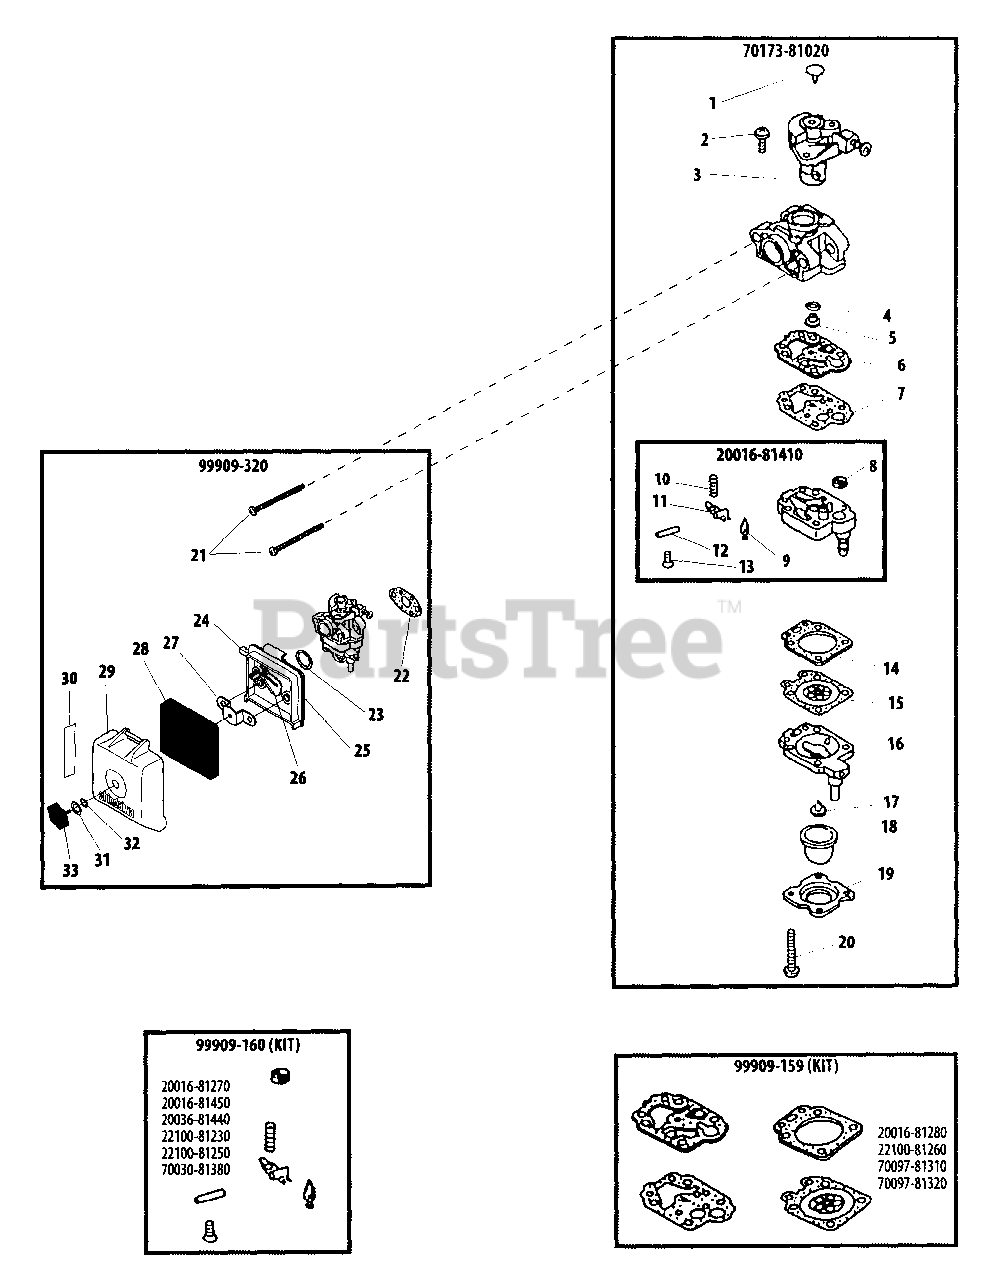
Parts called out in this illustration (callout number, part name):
1	PLUG
2	SCREW, THROTTLE COLLAR
3	THROTTLE VALVE ASSY
4	O-RING
5	MAIN JET - #38
6	GASKET, PUMP
7	DIAPHRAGM, PUMP
8	SCREEN, FUEL INLET
9	VALVE, INLET NEEDLE
10	SPRING, METERING LEVER
11	LEVER, METERING
12	PIN, METERING LEVER
13	SCREW
14	GASKET, METERING DIAPHRAGM
15	DIAPHRAGM, METERING
16	BODY ASSY, PURGE
17	VALVE, CHECK
18	BULB, PURGE
19	RETAINER, PURGE BULB
20	SCREW
21	SCREW - 5×67
22	GASKET, CARBURETOR
23	O-RING 15
24	LEVER, CHOKE
25	CASE, AIR FILTER
26	PLATE, CHOKE
27	BRACKET
28	FILTER, AIR
29	COVER, AIR FILTER
30	LABEL, CHOKE
31	WASHER, CONE M6
32	O-RING
33	THUMBSCREW
20016-81410	BODY ASSY, PUMP
70173-81020	CARBURETOR
99909-159	GASKET / DIAPHRAGM KIT
99909-160	VALVE KIT, INLET NEEDLE
99909-320	AIR FILTER ASSY
